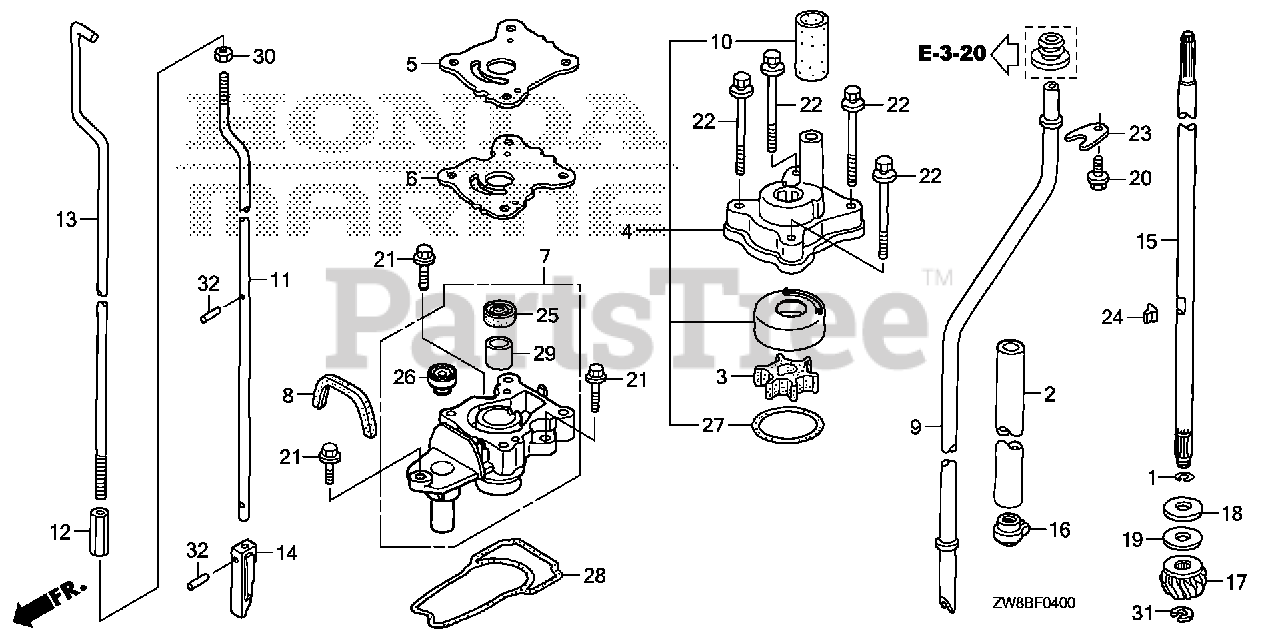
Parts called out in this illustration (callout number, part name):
1	CLIP, VALVE GUIDE
2	GUIDE, OIL (S,L)
3	IMPELLER, PUMP (S,L)
4	HOUSING ASSY., IMPELLER
5	COVER, IMPELLER
6	GASKET, IMPELLER
7	HOUSING, WATER PUMP (S,L)
8	GROMMET, WATER PUMP HOUSING
9	TUBE, WATER (S)
10	RING, WATER TUBE SEAL
11	ROD B, SHIFT (S)
12	JOINT, SHIFT ROD
13	ROD A, SHIFT (S)
14	ROD, PUSH
15	SHAFT, VERTICAL (S)
16	SLINGER, OIL (S,L)
17	GEAR, PINION
18	WASHER A, THRUST BEARING
19	WASHER B, THRUST BEARING
19	WASHER C, THRUST BEARING
20	BOLT, FLANGE (6X12)
21	BOLT, FLANGE (6X20)
22	BOLT-WASHER (6X50)
23	PLATE, WATER TUBE SETTING
24	KEY, WOODRUFF
25	SEAL, WATER (13MM) (ARAI)
26	SEAL, WATER (6MM)
27	O-RING (42.2X2.4)
28	O-RING, WATER PUMP HOUSING
29	BUSH (13X15X15)
30	NUT, HEX. (6MM)
31	E-RING (8MM)
32	ROLLER (2.5X11.8)
